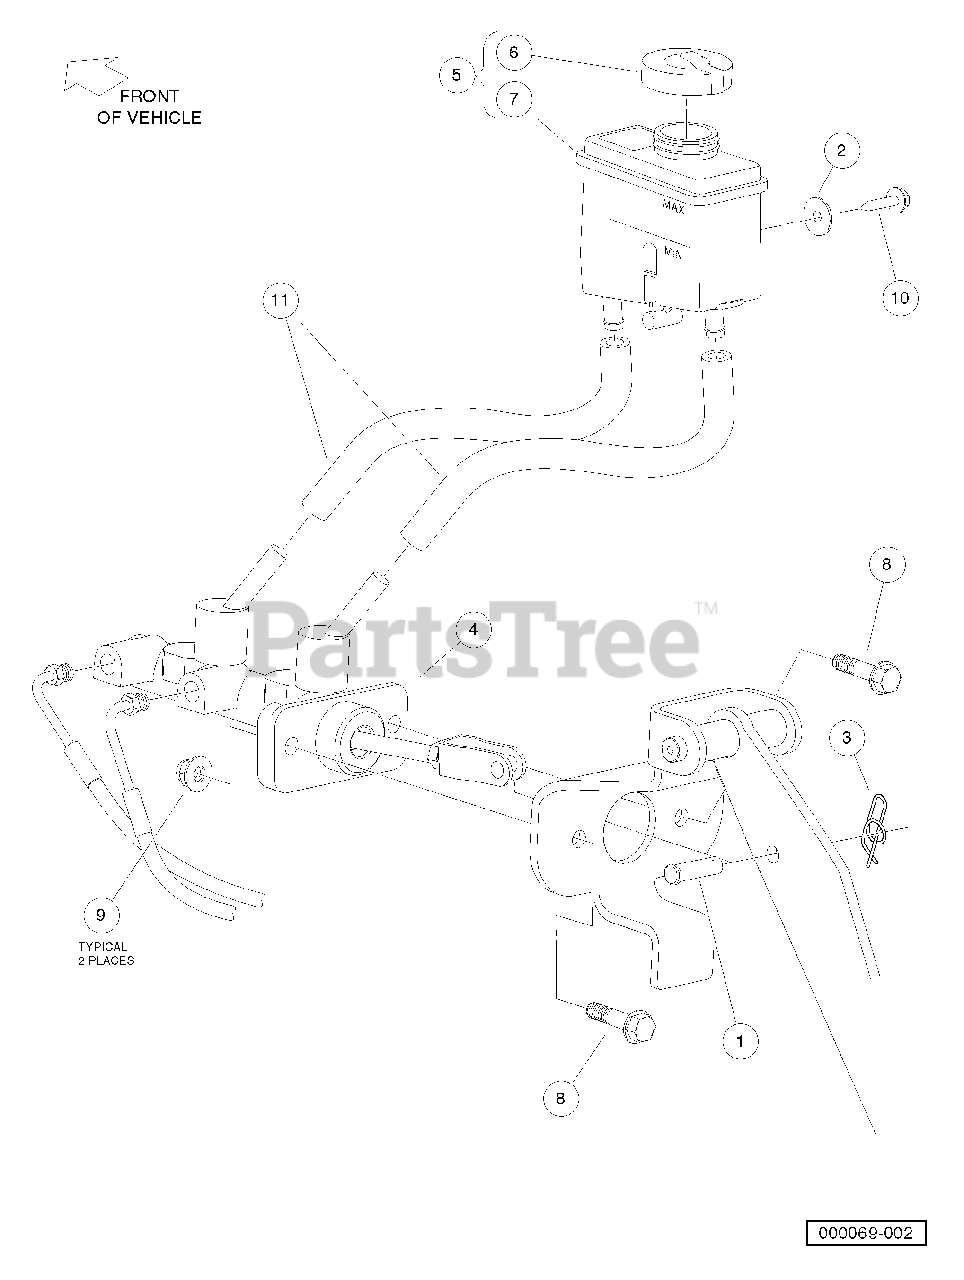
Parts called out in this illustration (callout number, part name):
1	Clevis Pin, 5/16 X 1
2	Washer, 1/4" Type B Flat
4	Cylinder, Master, Tandem
5	Assembly, Reservoir, Remote
6	Filler Cap Asm
7	Reservoir, Brake Fluid, Without Cap
8	Bolt Flanged Head, M8 X 1.25 X 35
9	Lock Nut, Flg M8 X 1.25 Nylon
10	Screw, #10x3.50 Ab Thd, Hex Hd
11	Hose, Reservoir, Brake Fluid
